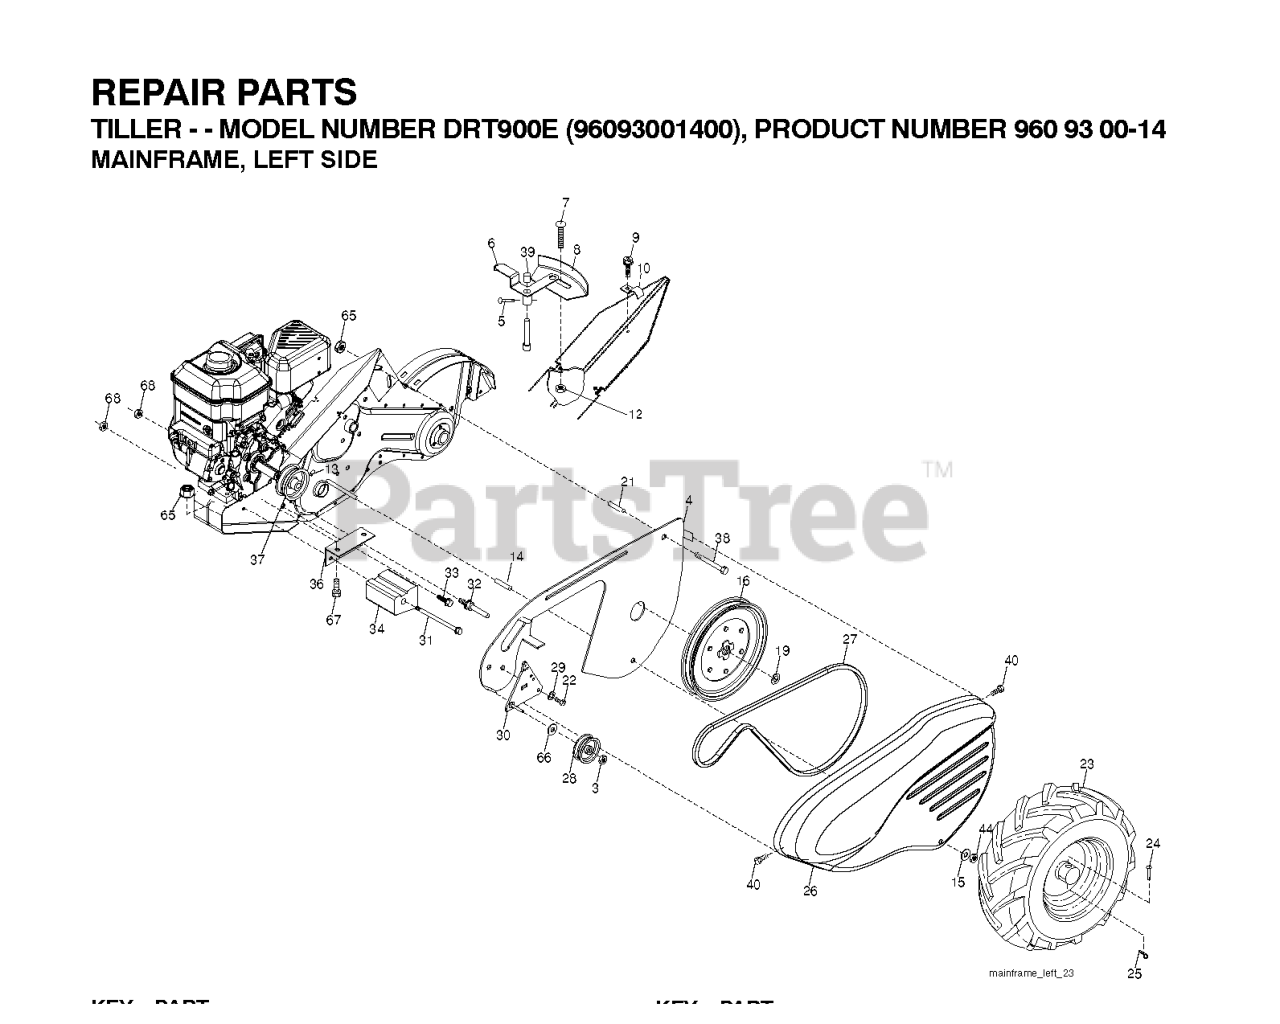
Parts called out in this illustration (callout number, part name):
3	LOCKNUT
4	SHIELD.INNER.BELT.GUARD.RT
5	PIN.SPIROL.FLARED
6	LEVER.ASM.SHIFT.RED
8	RP.PANEL.SHIFT
9	TAPPING SCREW
10	CONDUIT.CLIP.PLATED
12	NUT
14	SPACER CRT
15	WASHER
16	SHEAVE, TRANSMISSION
19	RETAINING RING LT
21	SPACER-SPLIT.327 X .42
23	TIRE.13X5-6.CHEVRON.TILLER
24	RIVET,DRILLED
25	RETAINER M
26	GUARD.BELT.TILLER.ORANGE
27	V-BELT
28	PULLEY-IDLER TI
30	BRACKET.ASM.IDLER.BLACK
31	BOLT.FIN.HEX.3/8-16UNC
32	SHIFT ARM CRT
33	BOLT
34	COUNTERWEIGHT.LH.CRT
36	BRACKET LH CRT
37	RP.ENGINE PULLEY
38	BOLT
39	CAP.PLUNGER.BLACK
40	SCREW.HEX.WSH.SLT.#10-24X.50
44	NUT.71038.31-18.HEX.NYLOCK
65	LOCKNUT-FLANGE 5/16-18
66	WASHER
67	BOLT
